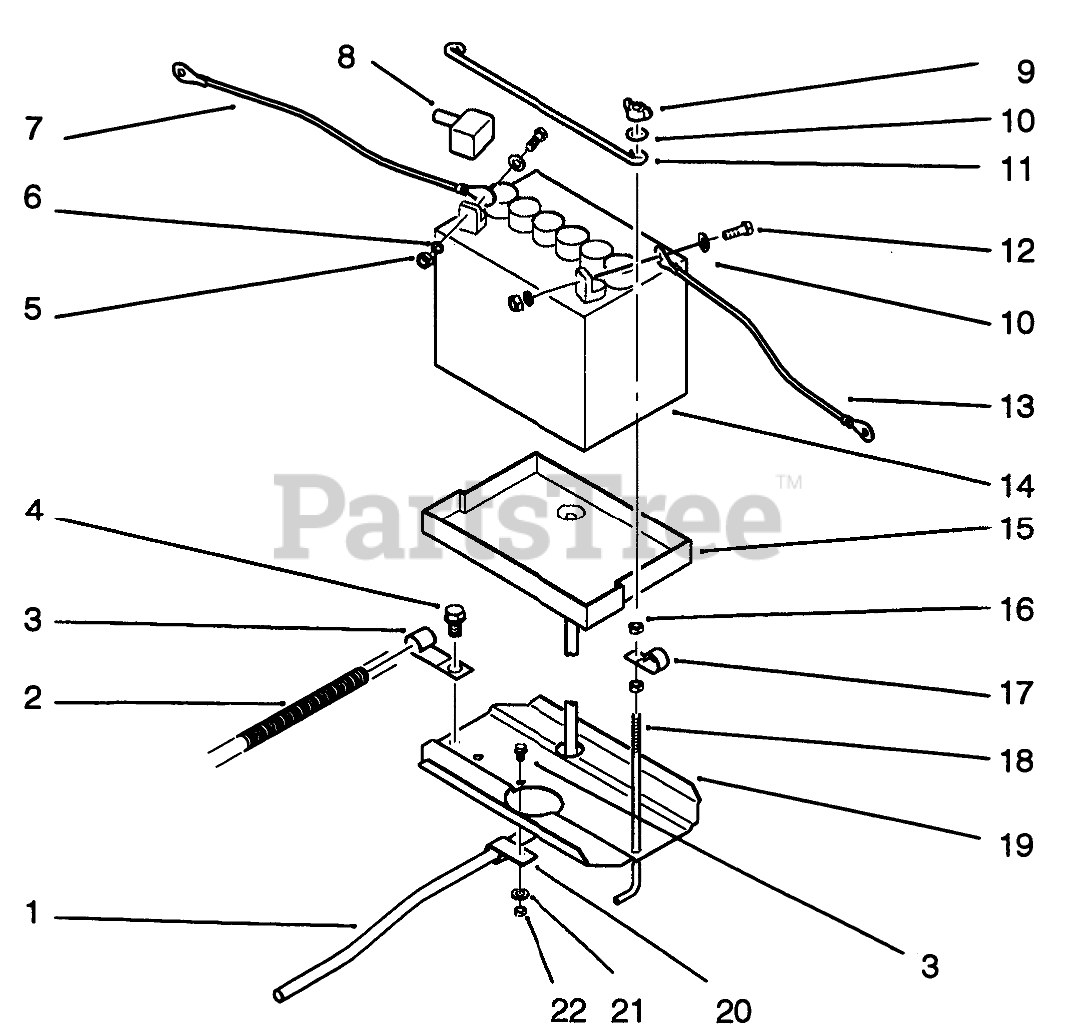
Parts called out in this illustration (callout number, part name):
1	TUBE-21" BATTERY DRAIN
2	WIRING-HARNESS & DIA
3	CLIP
4	Screw
5	NUT-HEX
6	WASHER-LOCK
7	WIRE - 14" BLACK
8	Boot
9	NUT-WING
10	WASHER-FLAT
11	ROD-BATTERY HOLD DWN
12	SCREW-HH
13	ASS'Y-WIRE
14	Battery
15	TRAY-BATTERY
16	Nut
17	CLAMP
19	Tray
20	WASHER-FLAT
21	NUT-LOCK, NI
22	NUT-LOCK, NI
